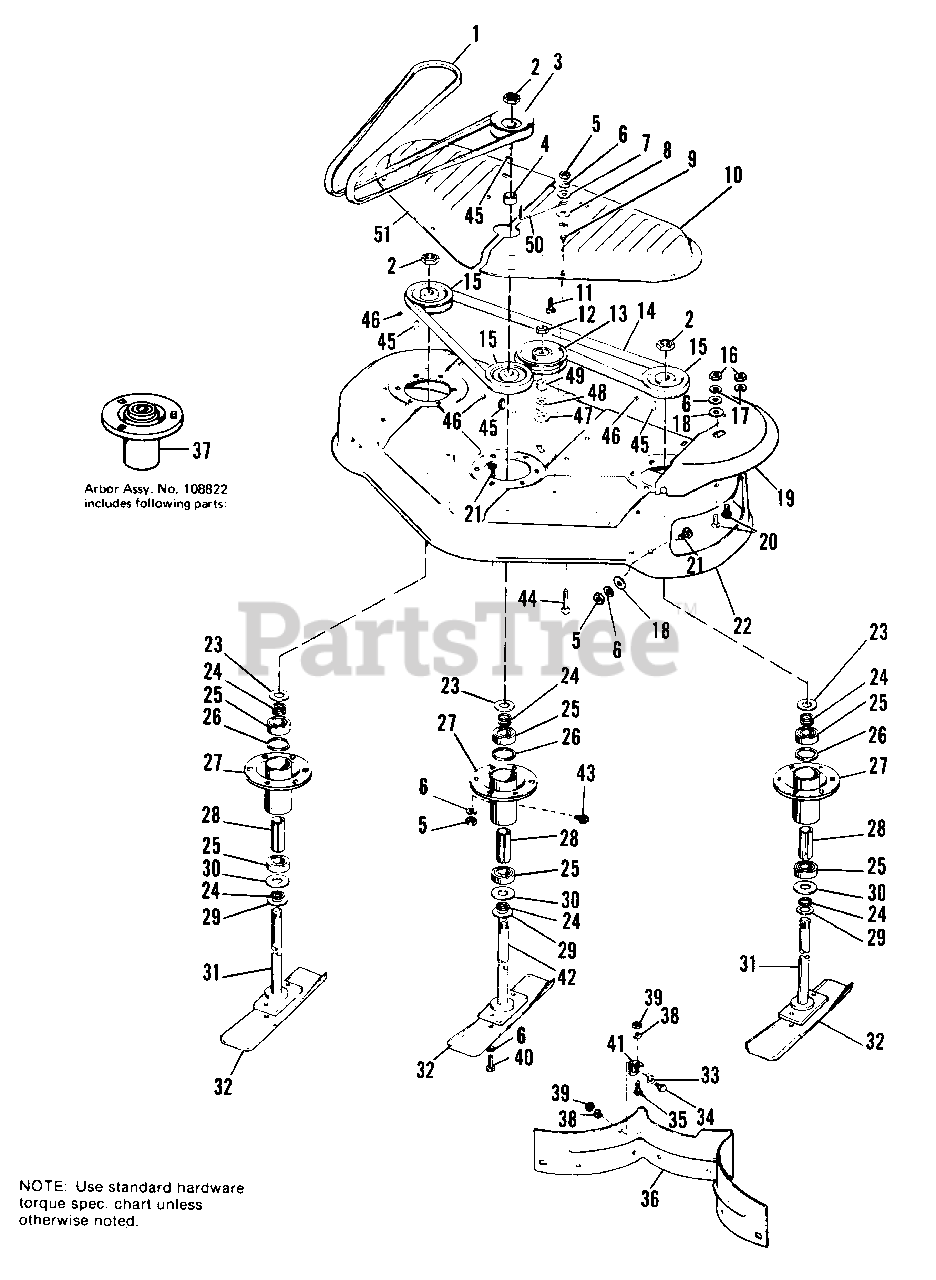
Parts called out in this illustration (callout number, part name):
1	V-BELT
1	V-BELT (990883 Only)
2	LOCKNUT, Hex, Jam, 3/4-16
3	PULLEY, Cross Drive
5	NUT, Hex, Full, 3/8-16
6	LOCKWASHER, 3/8
7	WASHER, Plain, 3/8
8	WASHER, Plain, 7/16
9	SCREW, Self Tapping, Hex Hd., 1/4-20 x 3/8
10	COVER, Half, L.H.
11	BOLT, Carriage, 3/8-16 x 1
12	LOCKNUT, Hex, 3/8-16
13	PULLEY, Idler
15	PULLEY (990883 Only)
16	NUT, Hex, Full, 5/16-18
17	LOCKWASHER, 5/16
18	WASHER, Special
19	DEFLECTOR
20	BOLT, Carriage, 5/16-18 x 3/4
21	BOLT, Carriage, 3/8-16 x 3/4
22	HOUSING KIT, 32"
25	BEARING, Ball
26	RING, Backing
27	TUBE ASSY., Arbor
31	ARBOR ASSY.
33	WASHER, Plain, 1/4
34	CAPSCREW, Hex Hd., 1/4-20 x 5/8
35	SCREW, Self Tapping, Hex Hd., 1/4-20 x 7/8
36	BAFFLE, Mower
37	ARBOR ASSY., W/Bearings
38	LOCKWASHER, 1/4
39	NUT, Hex, Full, 1/4-20
40	CAPSCREW, Hex Hd., 3/8-16 x 5/8
41	CLIP, Baffle
42	ARBOR ASSY., Drive
43	FITTING, Grease
44	BOLT, Carriage, 3/8-16 x 1-3/4
45	KEY, Woodruff, #61
46	SETSCREW, 5/16-18 x 3/8
47	WASHER, Plain, 1/2
48	WASHER, Plain, 5/16
50	STOP, Belt
51	COVER, R.H.
